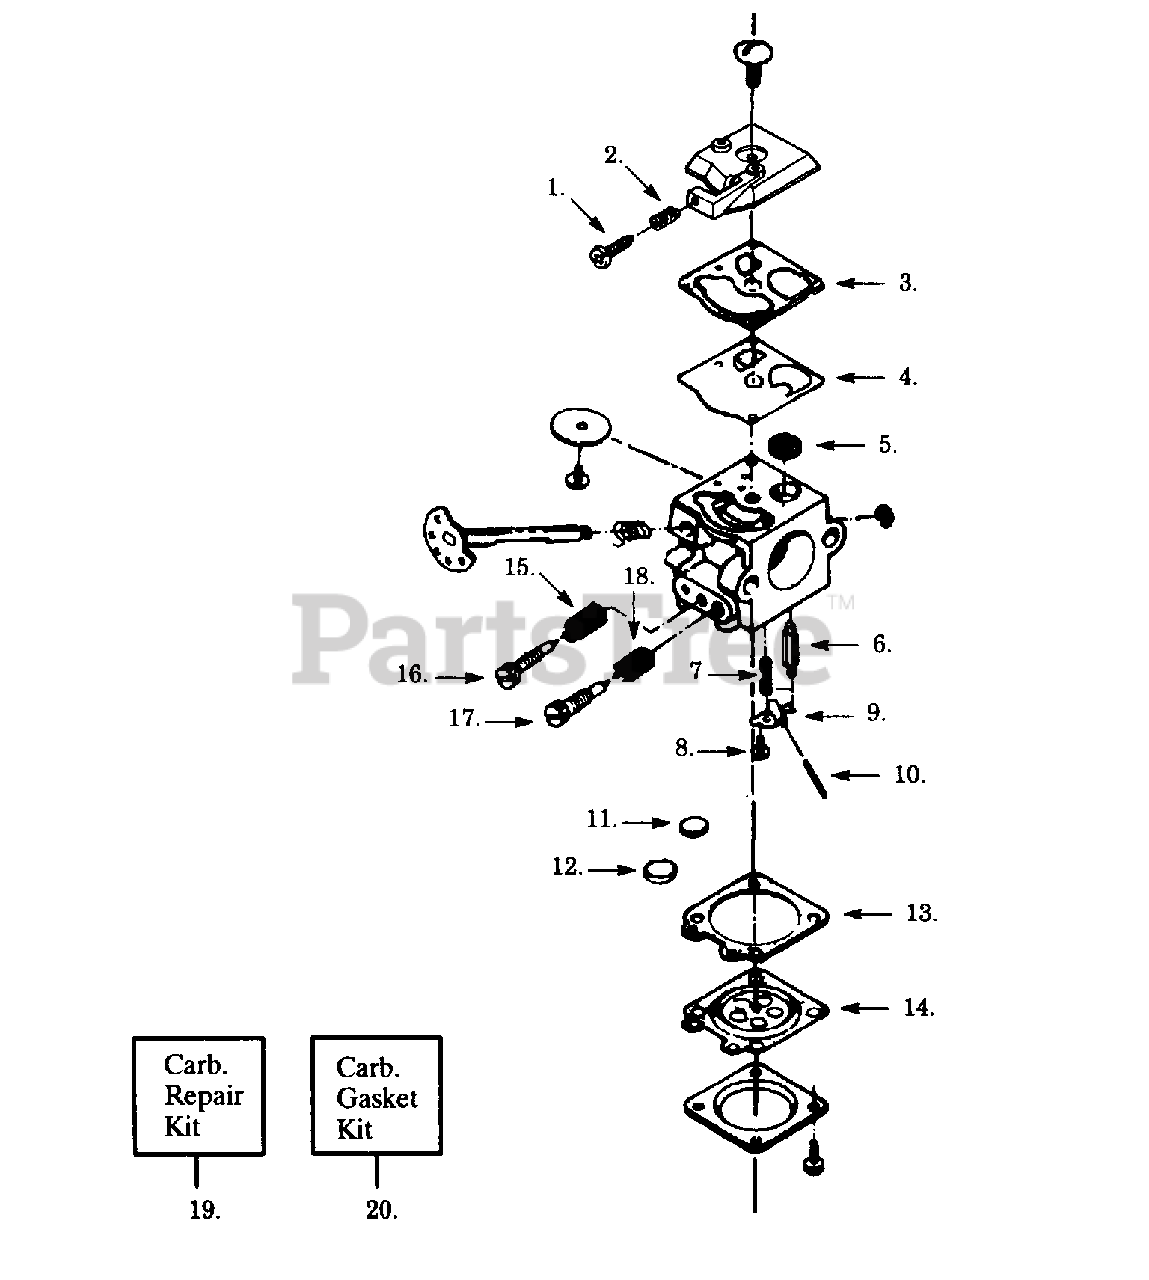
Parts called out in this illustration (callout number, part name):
1	Idle Speed Adj. Screw
2	Idle Speed Adj. Spring
3	Fuel Pump Gasket
4	Fuel Pump Diaphragm
5	Fuel Inlet Screen WT-3
5	Fuel Inlet Screen WT20/247
6	Inlet Needle Valve
7	Metering Lever Spring
8	Metering Lever Pin Screw
9	Metering Lever
10	Metering Lever Pin
11	Welch Plug-5/16 Dia.
12	Welchg Plug-1/4 Dia.
13	Metering Diaphragm Gasket
14	Metering Diaphragm
15	Low Speed Mixture Needle Spring
16	Low Speed Mixture Needle
17	High Speed Mixture Needle
18	High Speed Mixture Needle Spring
19	Carb. Repair Kit
20	Carb. Gasket/Diaphragm
